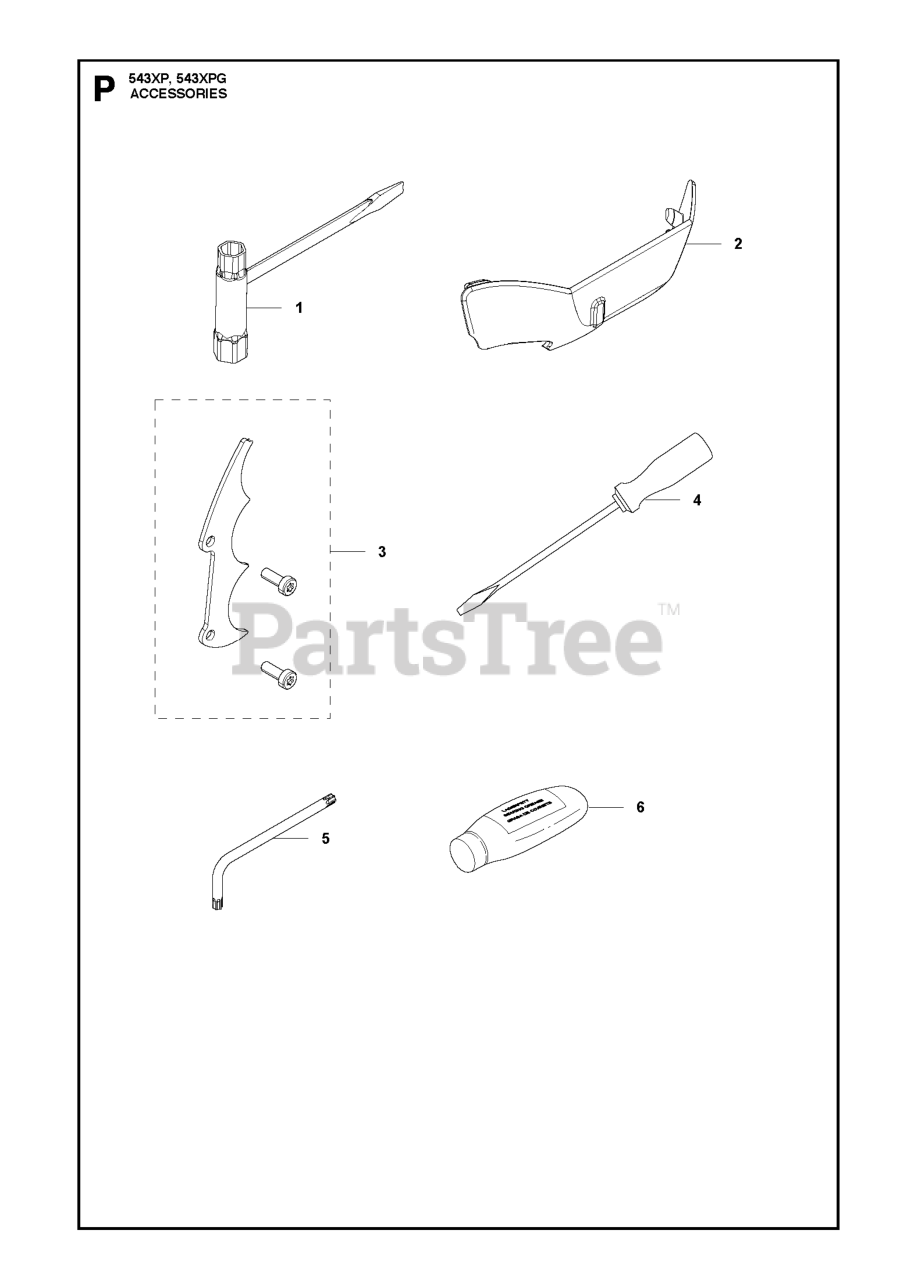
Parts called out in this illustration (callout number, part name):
2	WINTER COVER BLUE
3	SPIKE
5	ALLEN KEY
